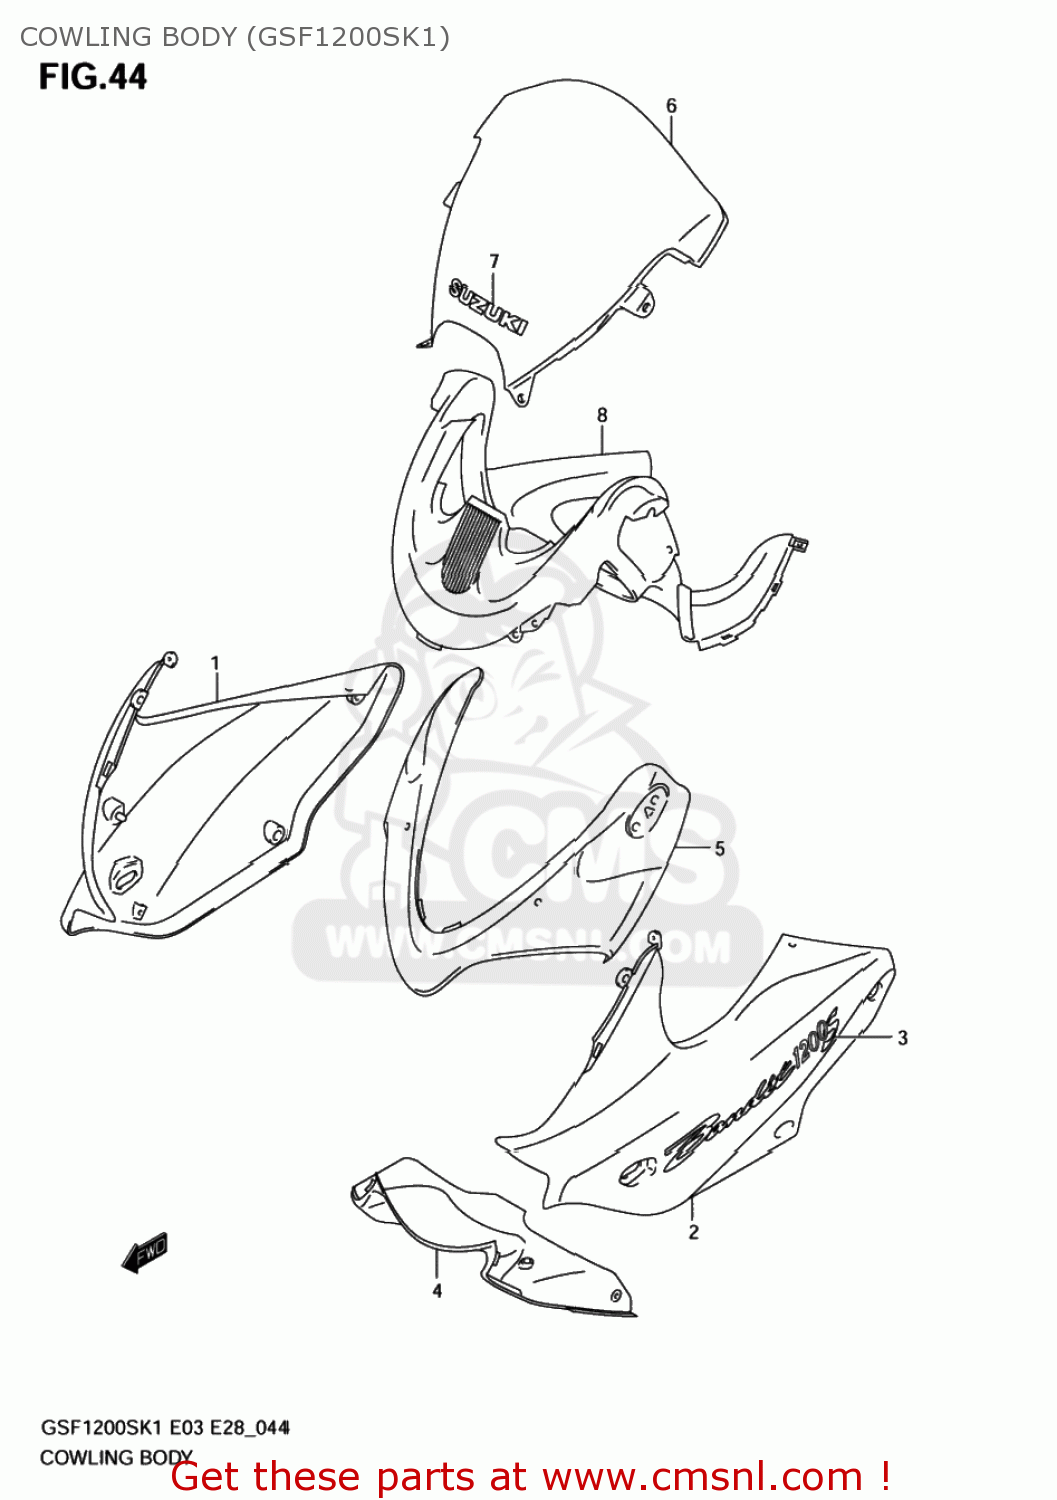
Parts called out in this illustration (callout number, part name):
1	COWLING ASSY,SIDE,R
2	COWLING ASSY,SIDE,L
3	EMBLEM,COWLING SIDE
4	COWLING,CTR(RED)
5	COWLING,FR
6	WINDSCREEN ASSEMBLY (SILVER)
7	EMBLEM,SUZUKI
8	PANEL,METER
